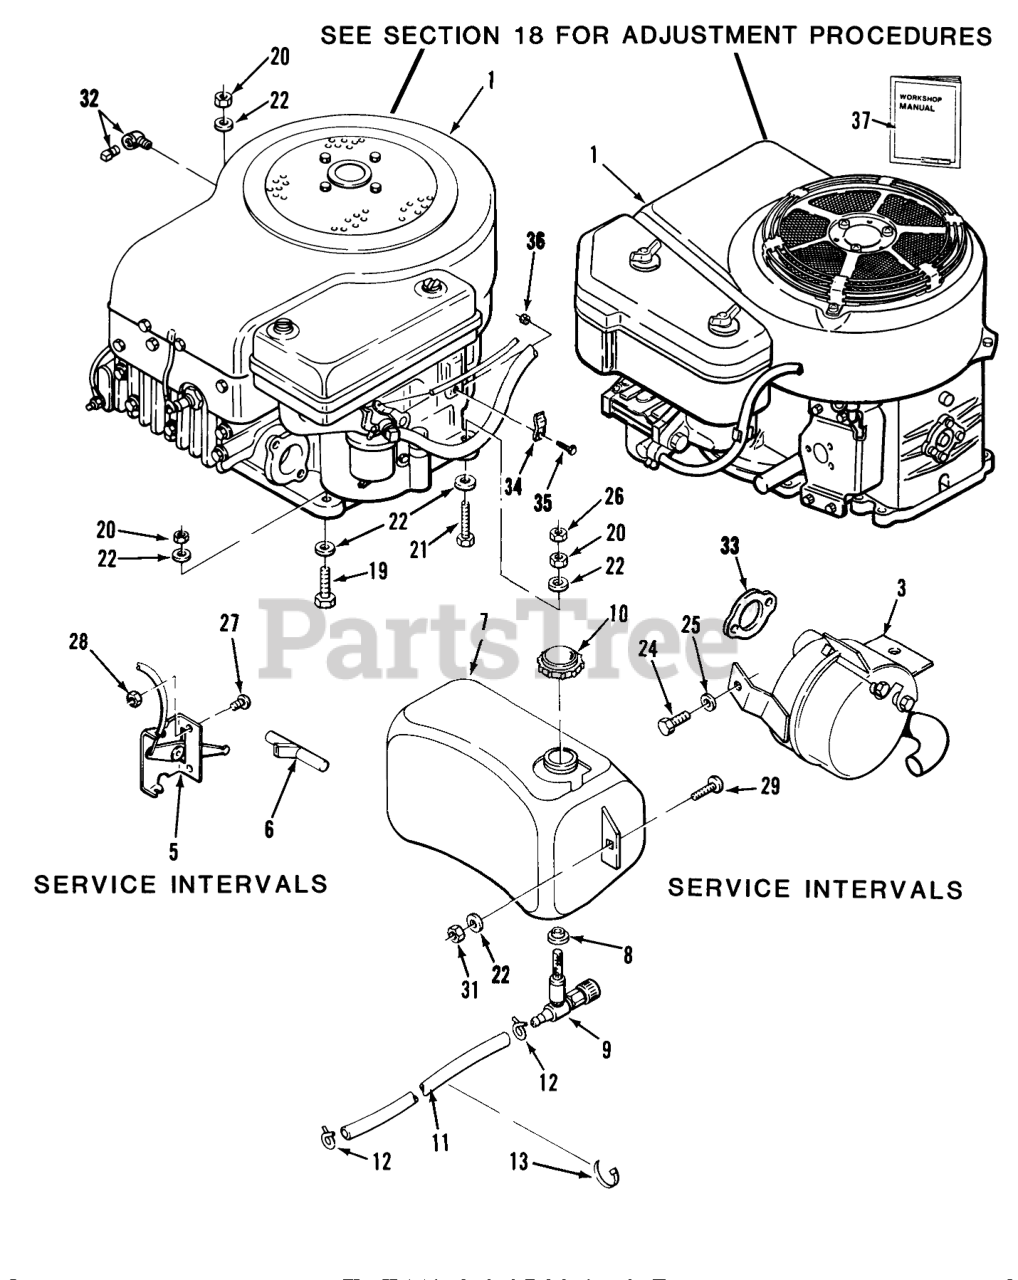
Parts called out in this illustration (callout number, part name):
1	Engine-8HP-B&S Model 191707, Type 2175-01 208-4 Only
1	Engine-11HP-B&S Model 252707, Type 0624-01 211-4 Only
1	Engine-11HP-B&S Model 253707, Type 0222-01 211-5 Only
1	Engine-12.5HP Kawasaki Model FB460V, Type AS/BS-13 212-6 Only (See sections 9-2 thru 9-7 for complete engine parts breakdown)
3	Muffler-Black (includes Bolts, Heat Deflector and Spacer) 208-5
3	Muffler-Black (includes Bolts, Heat Deflector and Spacer) 211-4 & 211-5
5	Choke/Throttle Control
5	CONTROL-THROTTLE
6	KNOB-CONTROL
7	Fuel Tank
8	BUSHING
9	Valve
10	CAP GAS
11	FUEL LINE 19" OF 6554
11	Fuel Line 22" 212-6
12	Clamp
13	PLASTIC TIE
19	HHCS
20	Nut
22	WASHER 5/16 SAE
24	Bolt
26	Nut
27	Screw
28	Nut
29	Bolt
31	Nut
32	STREET ELBOW 45DEGRE
33	Exhaust Gasket
34	CLAMP THROTTLE
35	SCREW THROTTLE
36	Throttle Screw Nut
37	Kawasaki FB460V Workshop Manual
